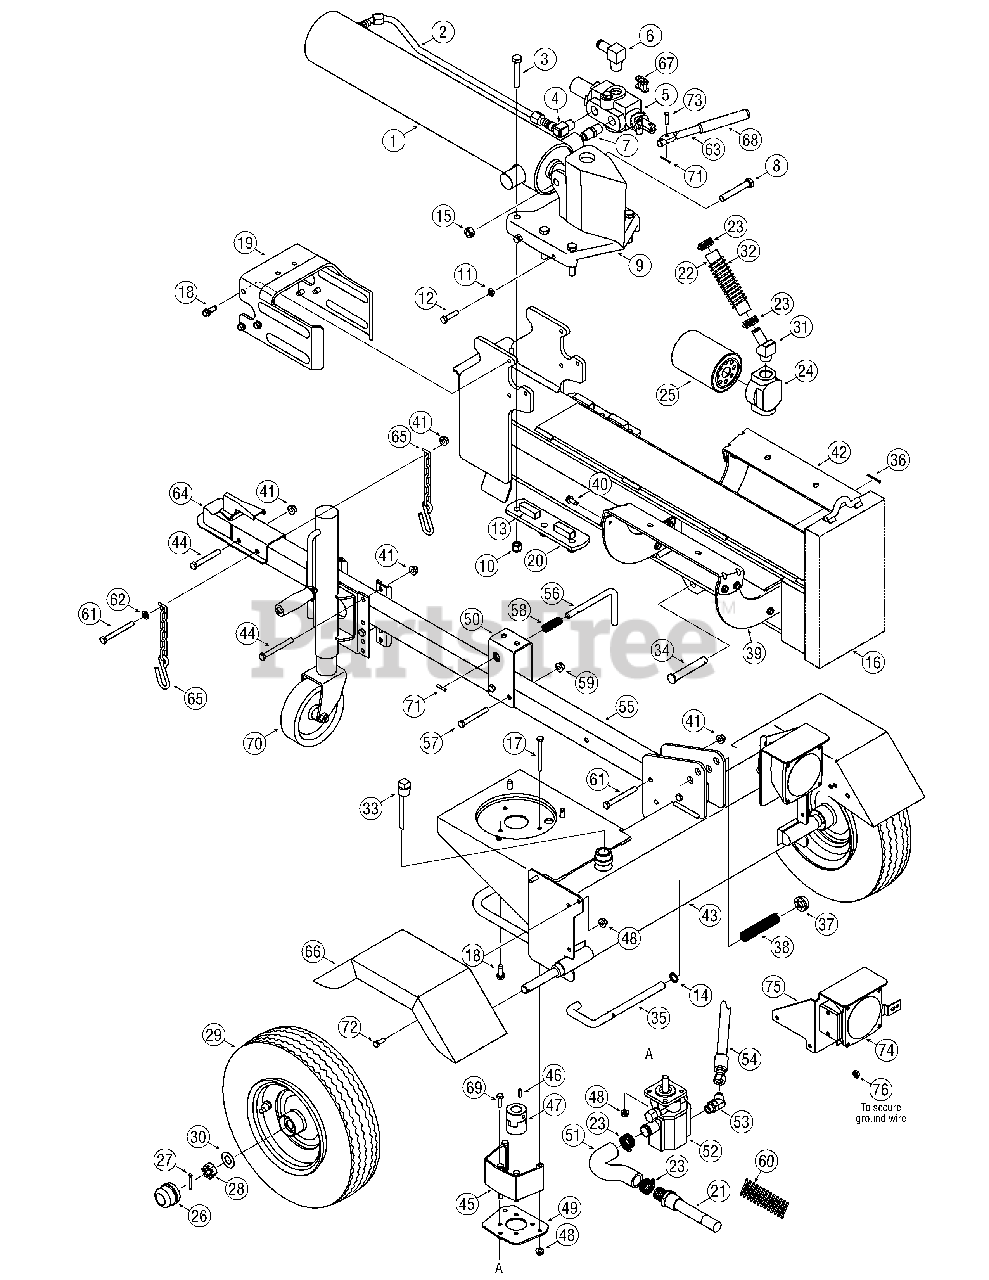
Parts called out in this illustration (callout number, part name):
1	Hydraulic Cylinder
1	Kit Seal 4.5" for XINGHUI cylinder 718-0769A
1	Kit Seal 4.5" for ENERGY cylinder 718-0769A
2	Hydraulic Tube
3	Hex Cap Screw 1/2-20 x 2.75
4	90 Degree Solid Adapter
5	Control Valve
6	Return Elbow
7	Nipple Pipe 1/2-14
8	Hex Cap Screw 1/2-13 x 3.25
9	Wedge Assembly
10	Hex Lock Nut, 1/2-20
11	Hex Jam Nut 3/8-24
12	Hex Cap Screw 3/8-24 x 1.5
13	Adjustable Gib
14	Flat Washer.635 x.93 x.06
15	Hex Lock Nut 1/2-13
17	Hex Screw, 5/16-18 x 3.25
18	Hex Washer Screw 3/8-16 x 1.0
21	Inlet Filter
22	Return Hose 3/4" ID x 44" Lg.
23	Hose Clamp 5/8"
24	Filter Housing
25	Oil Filter
27	Cotter Pin
28	Slotted Nut 3/4-16
29	Wheel Assembly
30	Flat Washer.760 ID x.500 OD
31	Adapter 3/4-14
32	Hose Guard
33	Vented Dipstick
34	Clevis Pin
36	Cotter Pin
38	Compression Spring
40	TT Screw, 5/16-18 x.875
41	Flange Lock Nut, 3/8-16
43	Frame Assembly
44	Hex Bolt 3/8-16 x 3"
45	Coupling Shield
46	Square Key 3/16" x.75
47	Flexible Coupling (Stamped L075) .875 x .500 ID
48	Flange Lock Nut, 5/16-18
52	Gear Pump
53	45 Degree Elbow Fitting
54	High Pressure Hydraulic Hose
56	Latch Rod
57	Hex Head Screw, 3/8-16 x 3
58	Compression Spring
59	Flange Lock Nut, 3/8-16
60	Hose Guard
61	Hex Cap Screw, 3/8-16 x 3.50
62	Flat Washer,.375 x.738 x.063
63	Hydraulic Valve Control
64	Hitch Coupling Assembly
67	Valve Handle Link
69	Hex Screw, 5/16-18 x 1.00
70	Adjustable Assembly Stand
71	Spirol Pin
72	TT Screw, 5/16-18 x 0.875"
73	Clevis Pin
74	Light Kit
76	Jam Nut, 3/8-16
